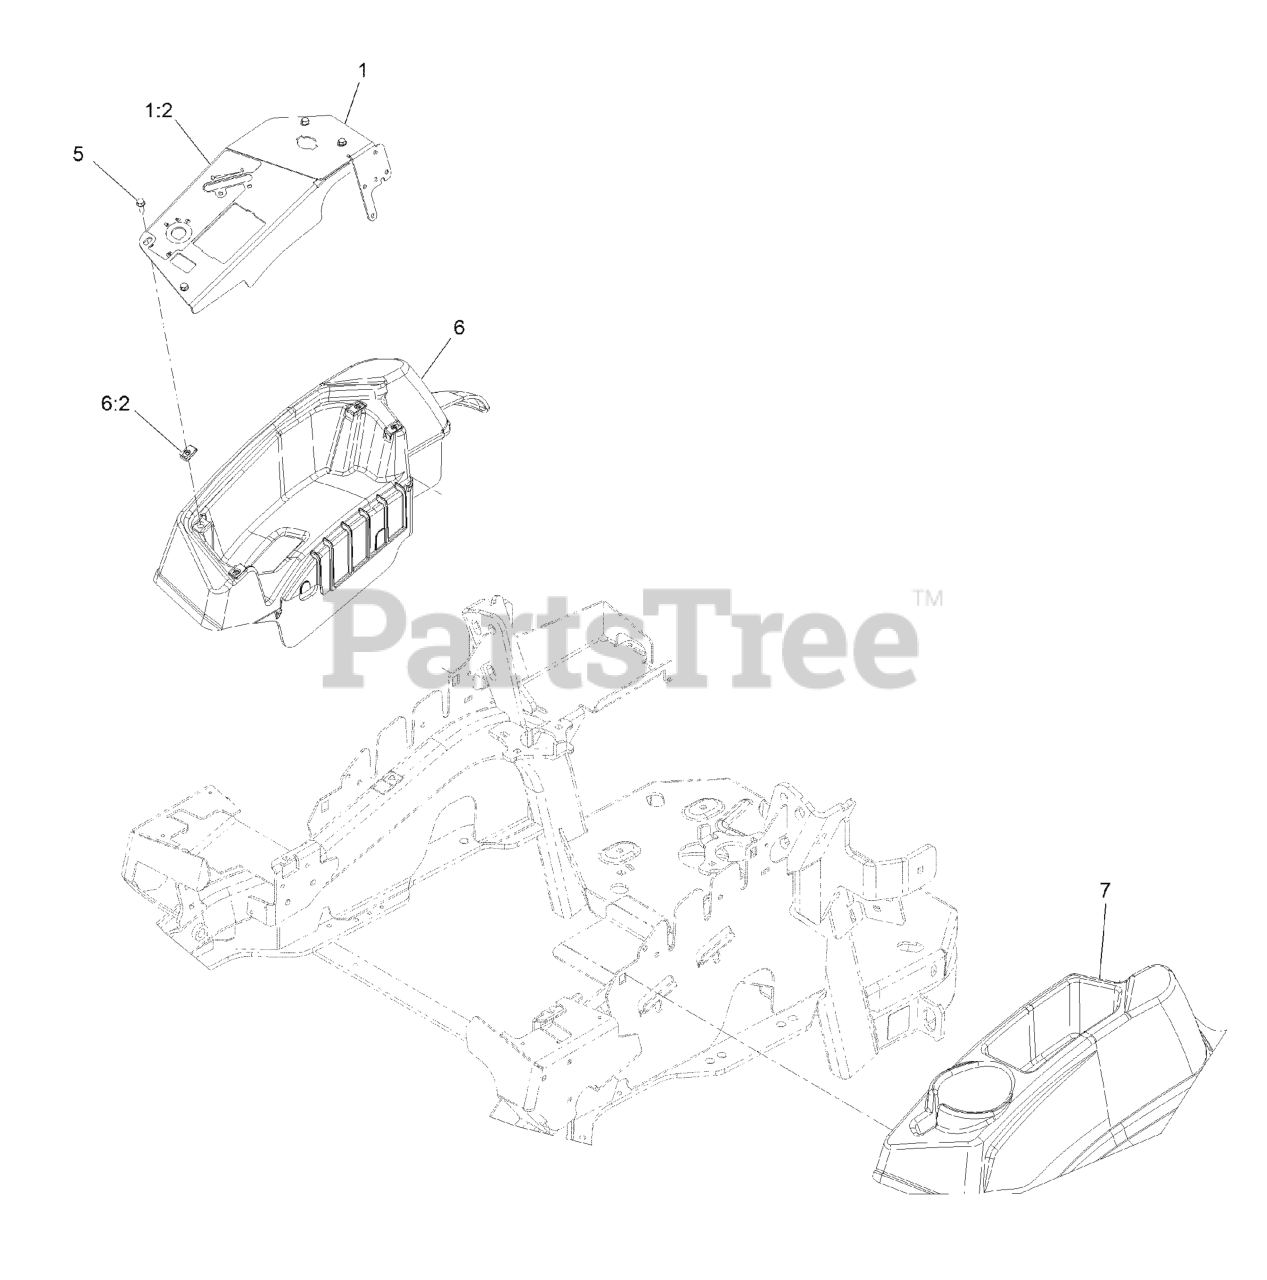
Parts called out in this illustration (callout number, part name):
1	ASM,CONTROL PANEL W/DECAL
1:2	DECAL-CONTROL PANEL EFI
1:3	DECAL-FUSES
2	ASM,THROTTLE CABLE
3	BOLT-CARR
4	NUT-LOCK, NI
5	SCREW-HWH
6	CONSOLE,RH AS ASM
7	CONSOLE, LH AS
8	PLUG-PLASTIC
9	CLAMP-HOSE
